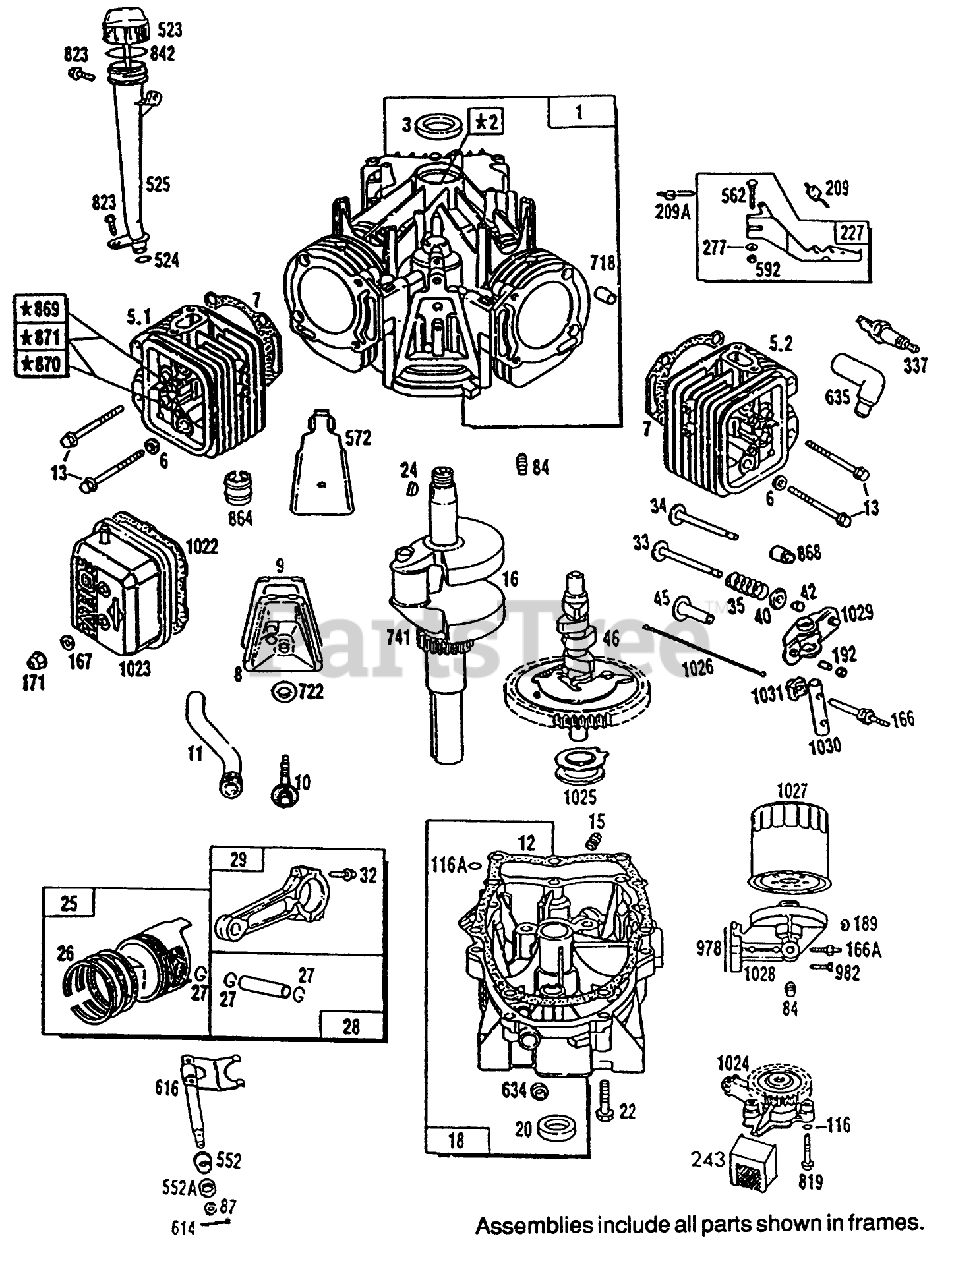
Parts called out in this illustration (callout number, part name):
1	BRIGGS-807511
3	BRIGGS-805101
6	BRIGGS-805193
7	BRIGGS-807986
9	BRIGGS-805379
11	BRIGGS-805362
12	BRIGGS-805312
13	BRIGGS-805097
18	BRIGGS-807638
20	BRIGGS 805049
22	BRIGGS-805017
24	BRIGGS-805016
26	BRIGGS-870620
27	BRIGGS 805099
28	BRIGGS-807621
29	BRIGGS-807622
32	BRIGGS-805395
33	BRIGGS-807681
34	BRIGGS-807680
35	BRIGGS 805078
40	BRIGGS-805092
42	BRIGGS-807683
45	BRIGGS 805354
46	BRIGGS-807542
84	BRIGGS-805059
87	BRIGGS-805054
116	BRIGGS-805058
116A	BRIGGS-805198
166A	BRIGGS 805073
167	BRIGGS-805420
171	BRIGGS 805019
189	BRIGGS-805449
192	BRIGGS-807623
209	BRIGGS-805562
209A	BRIGGS-805453
243	BRIGGS-805312
277	BRIGGS-805018
337	SPARK PLUG
351	BRIGGS 805169
523	BRIGGS-807516
524	BRIGGS 807663
552	BRIGGS-805412
552A	BRIGGS-805413
562	BRIGGS 805381
572	BRIGGS-805197
592	BRIGGS-805395
614	BRIGGS 805417
616	FORK-GOVERNOR
634	BRIGGS 805416
635	BRIGGS 805529
718	BRIGGS-805103
741	BRIGGS-805675
819	BRIGGS 805057
823	BRIGGS 805317
842	BRIGGS-805012
864	BRIGGS 805083
868	BRIGGS-805094
869	BRIGGS-805085
870	BRIGGS-805086
871	BRIGGS-805084
978	BRIGGS 805250
982	BRIGGS-805030
1022	BRIGGS-805028
1023	BRIGGS-805100
1024	BRIGGS-807546
1025	BRIGGS-805313
1026	OBTAIN LOCALLY
1028	BRIGGS 805292
1029	BRIGGS-807557
1030	BRIGGS-805342
